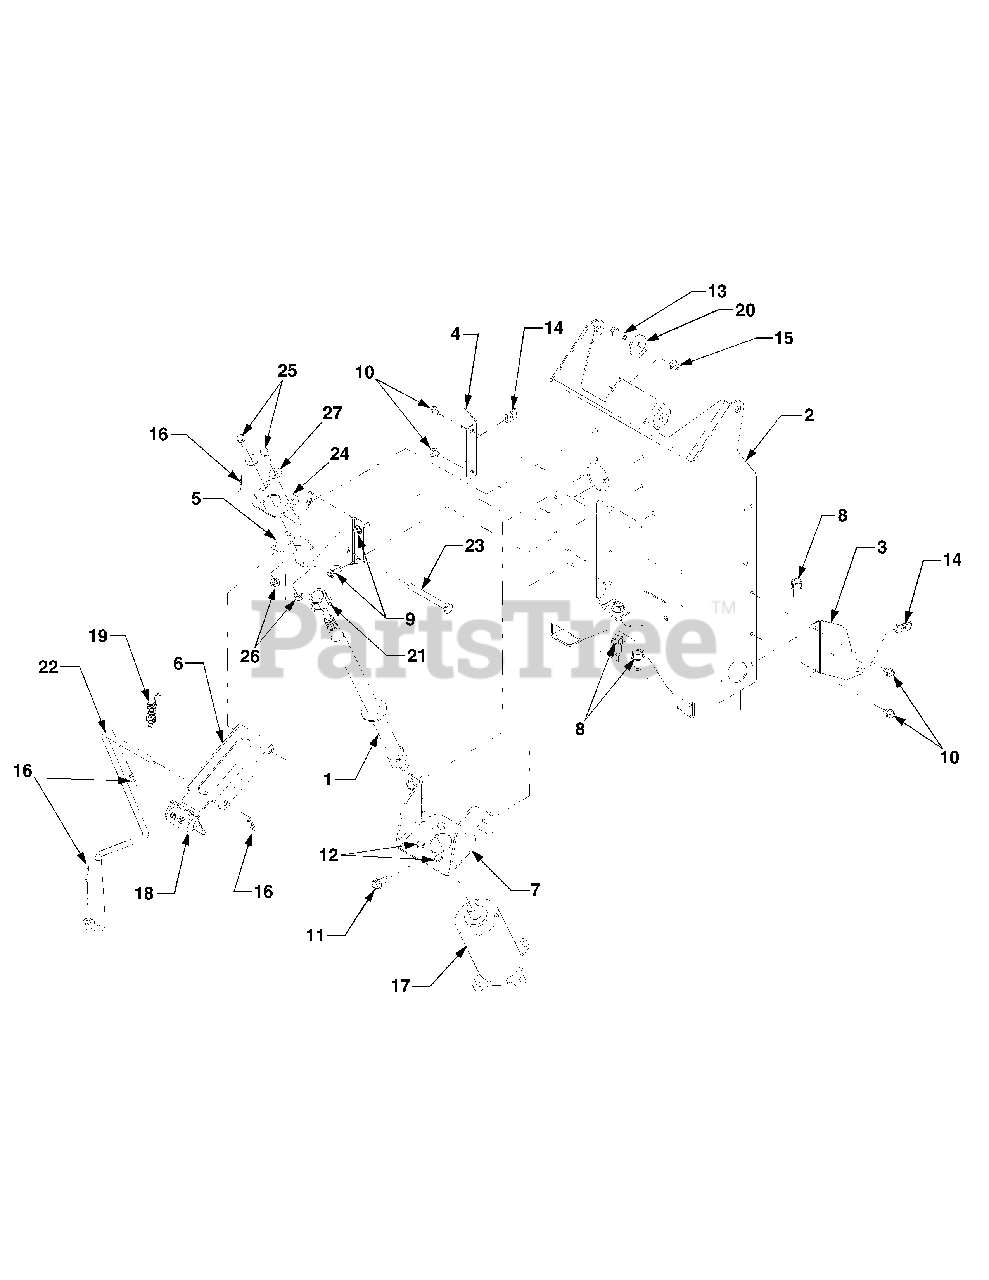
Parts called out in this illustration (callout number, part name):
1	Shaft, Steering - Mfg. Code 1B065G and before
1	Shaft, Steering - Mfg. Code 1B075G and after
2	Pedestal - Mfg. Code 1B065G and before
2	Pedestal - Mfg. Code 1B075G and after
3	Bracket, Dash Mtg. RH
4	Bracket, Dash Mtg. LH
5	Bracket, Steering Column
6	Bracket, Brake Lever
7	Bracket, Pump Mtg.
8	Screw, Hex Wash, Hd Tapp 3/8-16 x .75
9	Screw, Hex Wash, Hd Tapp 1/4-20 x .75
10	Screw, Hex Wash, Hd Tapp 1/4-20 x .375
11	Screw, Hex Wash, Hd Tapp 5/16-18 x .75
12	Screw, Hex,
13	Screw, Hex Cap 5/16-18 x .75 GR5
14	Nut, Speed, 1/4-20
15	Nut, Hex Flange Lock, 5/16-18
16	Pin, Internal Cotter
17	Pump, Hydraulic Steering
18	Lever, Parking Brake
19	Spring, Extension
20	Washer, Flat, .33 x 1.25 x .12 ...
21	Bearing, Hex Flange, .75 ID
22	Rod, Parking Brake
23	Pin, Parking Brake Pivot
26	Nut, Hex Insert Lock, 1/4-20
27	Washer, Flat, .28 x .74 x .063
